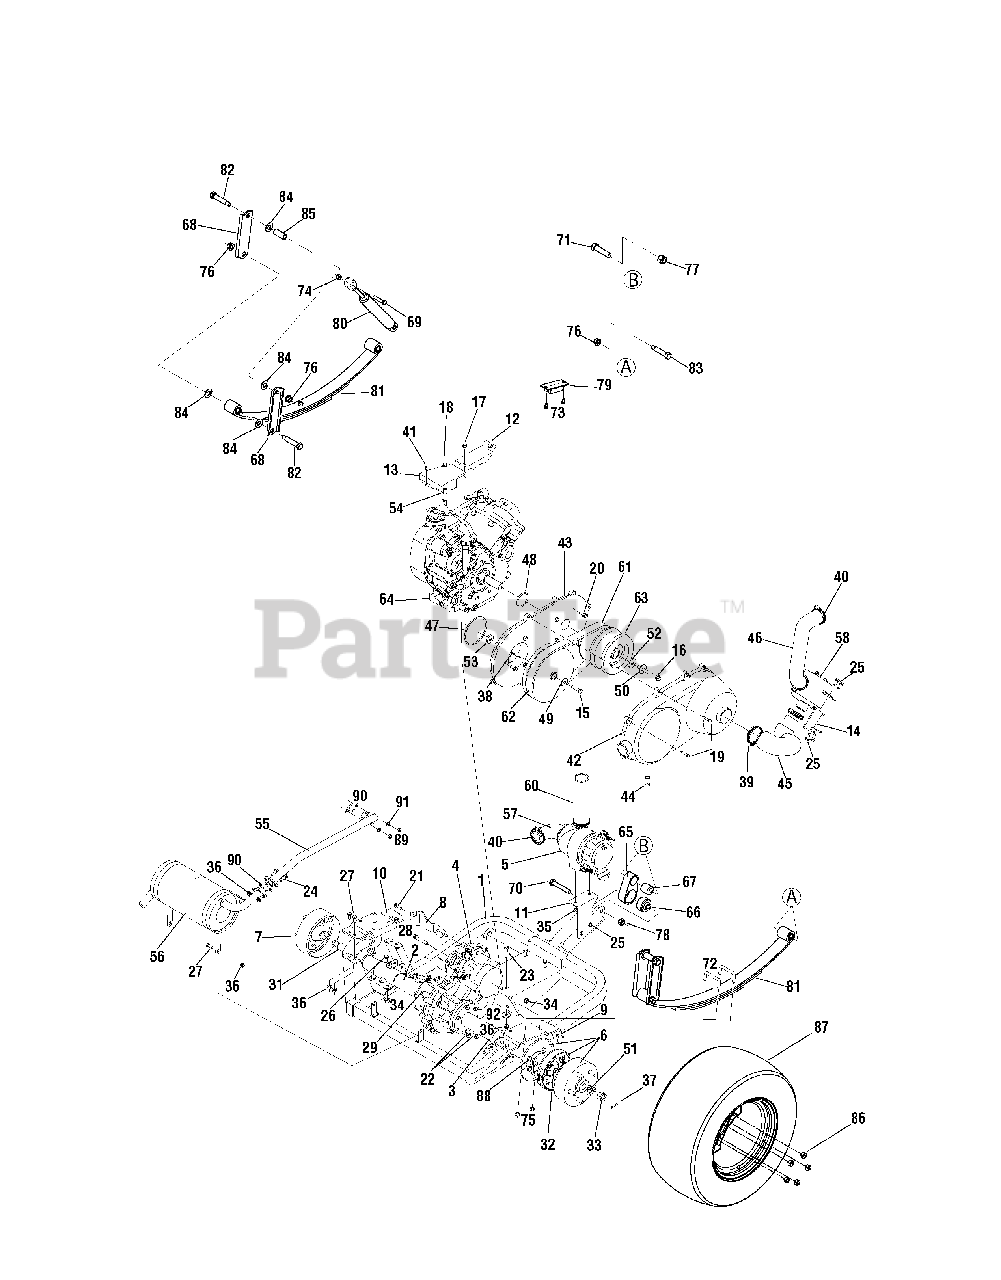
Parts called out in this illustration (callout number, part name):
3	Pipe Assembly - RH
4	Kawasaki Gear Assembly
5	Kawasaki Filter Assembly
6	Brake Assembly w/Drum - RH
6	Brake Assembly w/Out Drum - RH
7	Brake Assembly w/Drum - LH
7	Brake Assembly w/Out Drum - LH
8	Transmission Bracket
13	Cont: Cvr
14	Kawasaki Filter Bracket
15	Hex Screw, M8-1.25
16	Hex Flange Screw, M10 x 102MM
17	Hex Flange Screw, M8-1.25
18	Hex Flange Screw, 8MM x 1.125
19	Hex Flange Screw, M6 x 1.00
20	Flange Screw, M8 x 1.125
21	Flange Screw, M8 x 1.125
22	Flange Screw, M8 x 1.125
23	Hex Screw, 5/16-18 x 1.50
24	Hex Screw, 5/16-18 x.875
25	Screw, 5/16-18 x.750
26	Hex Screw, 3/8-16 x 1.00
27	Hex Screw, 5/16-18 x.75
28	Hex Screw, 3/8-16 x 2.25
29	Hex Screw, M8-1.25
31	OPP Transmission Axle - LH
32	OPP Transmission Axle - RH
33	Nut, M18-1.5
34	Flange Lock Nut, 3/8-16
35	Hex Nut, M8-1.25
36	Flange Lock Nut, 5/16-18
37	Cotter Pin, 5/32 x 1.25
38	Kawasaki Key
39	Adj. Hose Clamp
40	Adj. Hose Clamp
41	Blind Rivet
42	Case - RH
43	Case - LH
44	Boot
45	Duct
46	Duct
47	Kawasaki O-Ring
48	Kawasaki O-Ring, 50 x 4
49	Kawasaki Washer, 8.5 x 38 x 4
50	Kawasaki Washer, 10 x 32 x 4.5
51	Washer, 34MM x 18MM x 4MM
52	Kawasaki Spacer w/ Key
53	Kawasaki Spacer
54	Spacer, 9 x 13 x 17.2
55	Kawasaki Exhaust Pipe
56	Kawasaki Exhaust Muffler
57	Kawasaki Air Filter Hose
58	Kawasaki Air Filter Assembly 11010-1735
60	Kawasaki Airbox Hose
61	Kawasaki Belt
62	Kawasaki Driven Pulley
63	Kawasaki Drive Pulley
64	Engine
65	Bushing Plate
67	Bearing, 63ID x 1.19OD x 1.25
68	Shackle Plate
69	Hex Screw, 3/8-16 x 1.75
70	Hex Screw, M12-1.75 x 75MM
71	Hex Screw, 5/8-11 2.5 Lg.
72	OPP Transaxle U Bolt
73	Self Tap Screw, 1/4-20 x.500
74	Hex Lock Nut, 3/8-16
75	Hex Lock Nut, 3/8-24
76	Flange Lock Nut, 7/16-20
77	Hex Lock Nut, 5/8-11
78	Flange Lock Nut, M12-1.75
79	Extension Suspension Bumper
80	Shock Absorber, 2.50 Stroke
81	Leaf Spring
82	Shoulder Screw,.550 x 2.290
83	Shoulder Screw,.550 x 2.13
84	Thrust Bearing,.56 ID x 1.25OD x.06
85	Bushing,.75OD x.562ID x 1.75
86	Lug Nut, 7/16-20
87	Wheel Assembly, 23 x 10.5 x 12 RH
88	Hex Screw, 10-1.25 x 16MM
89	Hex Nut, M8-1.25
90	Kawasaki Exhaust Pipe Gasket
91	Lock Washer, 8MM
92	Flat Washer .344 x 1.125 x .12
